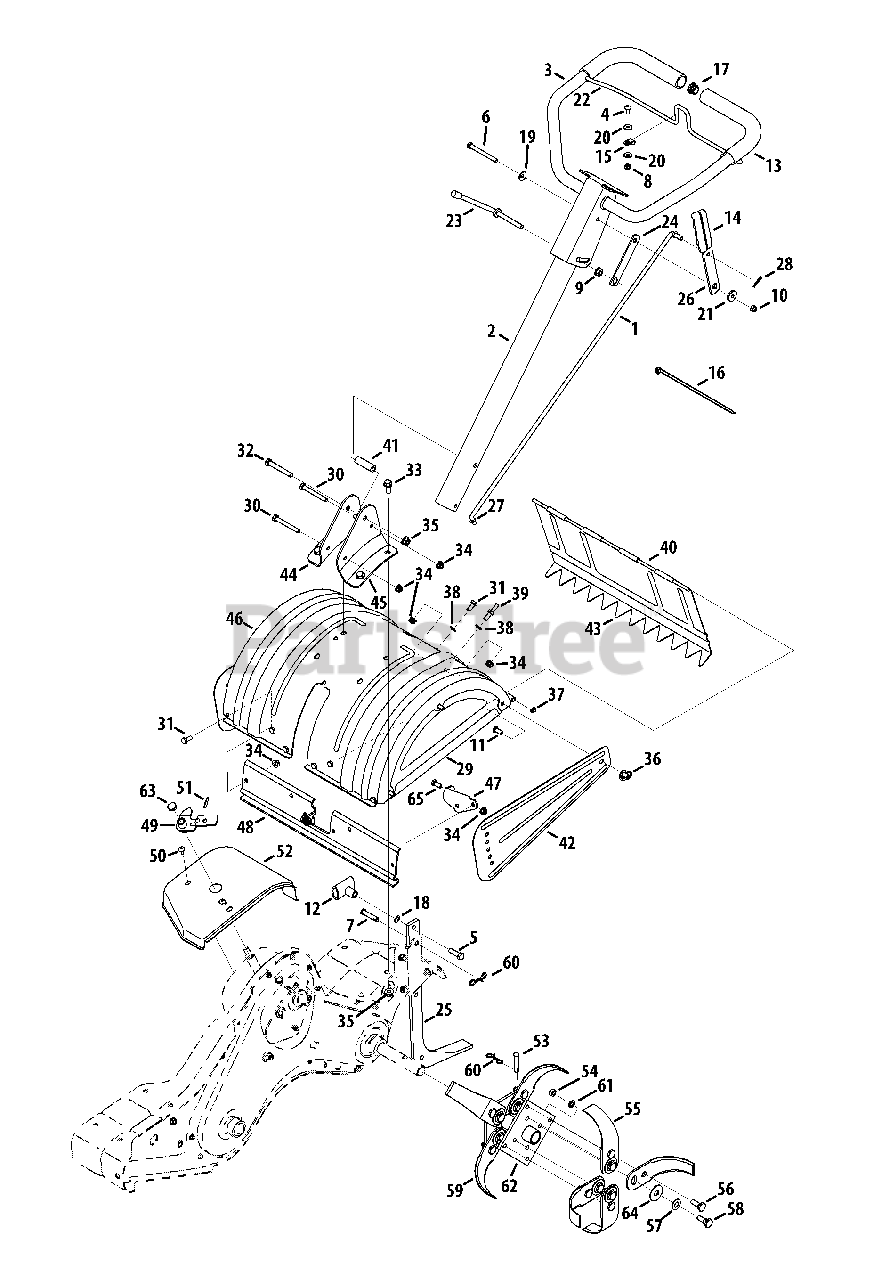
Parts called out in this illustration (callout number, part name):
1	Shaft Rod
2	Lower Handle Tube Assembly
3	Upper Handle Assembly
4	Screw, 1/4-20 x 0.625
5	Hex Head Screw, 3/8-16:1.25
6	Hex Head Screw, 5/16-18 x 3.25
7	Clevis Pin, .375 X 1.75
8	Hexlock Nut, 1/4-20
9	Flangelock Nut, 3/8-24
10	Hexlock Nut, 5/16-18
11	Stud, 5/16-18 x .75
12	Small Tee Knob
13	Foam Grip, .970 x 11.0
14	Grip, .1875 x 1.00
15	Battery Clamp, 5/16
16	Cable Tie, 8.5 LG
18	Washer, Flat, .385 x .620 x .033
19	Washer, Bell, .340 x .872 x .060
20	Washer, Flat, .260 x .720 x .060
21	Spacer, Shoulder, .50 x .190 x .360
23	Handle Adjustment Crank
24	Hex Nut Retainer Bracket
25	Tiller Depth Control
26	Shaft Rod Lever
27	Washer, Rubber, .33 ID x .125
28	Cotter Pin, .072 x 1.12 LG
29	End Cover Assembly
30	Hex Head Screw, 5/16-18 x 2.75
31	Hex Head Screw, 5/16-18 x .75
32	Hex Head Screw, 3/8-16 x 2.75
33	Hex Head Flange, 3/8-16 x .875
34	Flangelock Nut, 5/16-18
35	Flangelock Nut, 3/8-16
36	Wing Nut, 5/16-18 W/ Bell Washer
37	Speed Nut Cap, 1/4 ROD
38	Washer, Flat, .344 x .62 x .033
39	Screw, Hex, 5/16-18 x .75
40	Tiller Flap Rod
41	Spacer, .322 x .625 x 2.00
43	Rear Tine Shield
44	RH Handle Mount Bracket
45	LH Handle Mount Bracket
47	FRT Tine Shield Bracket
48	FRT Tine Shield Spacer Bracket
49	Shift Crank Assembly
50	Screw, 1/4-20 x .625
51	Spiral Pin, 3/16 x 1.0
53	Clevis Pin
54	Hex Nut, 3/8-24
55	13" Articulating Tine
56	Shoulder Bolt
57	Bell Washer, .515" ID x 1.14" OD
58	Shoulder Bolt
59	Tine Adapter Assembly, 18"
60	Internal Cotter Pin
61	Lock Washer
62	Tine Adapter Plate
64	Washer, Flat, .51 x 1.5 x .07
65	Hex Head Screw, 5/16-18 x 1.00
